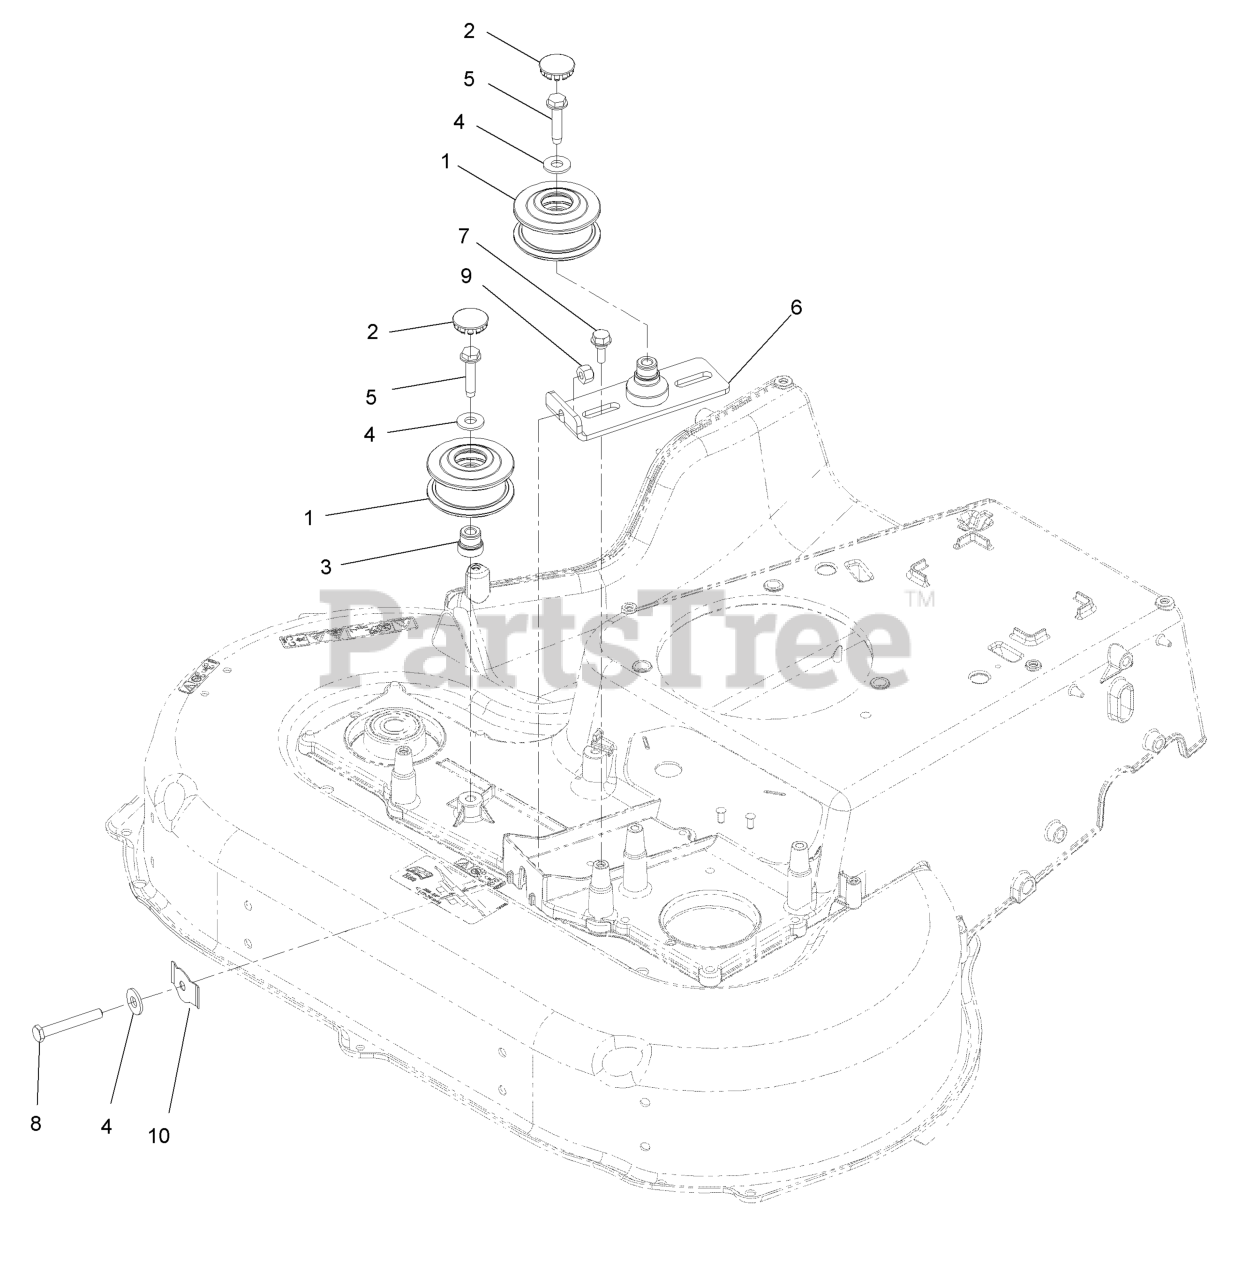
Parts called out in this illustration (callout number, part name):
1	Pulley-Idler, Flat
2	Plug-Button
3	Adapter-Bore
4	Washer-Flat
5	Screw-HWH
6	Bracket-Idler
7	Screw-Shoulder, HHF
8	Bolt-TAP, HH
9	Nut-Lock, NI
10	Spring-Flat
